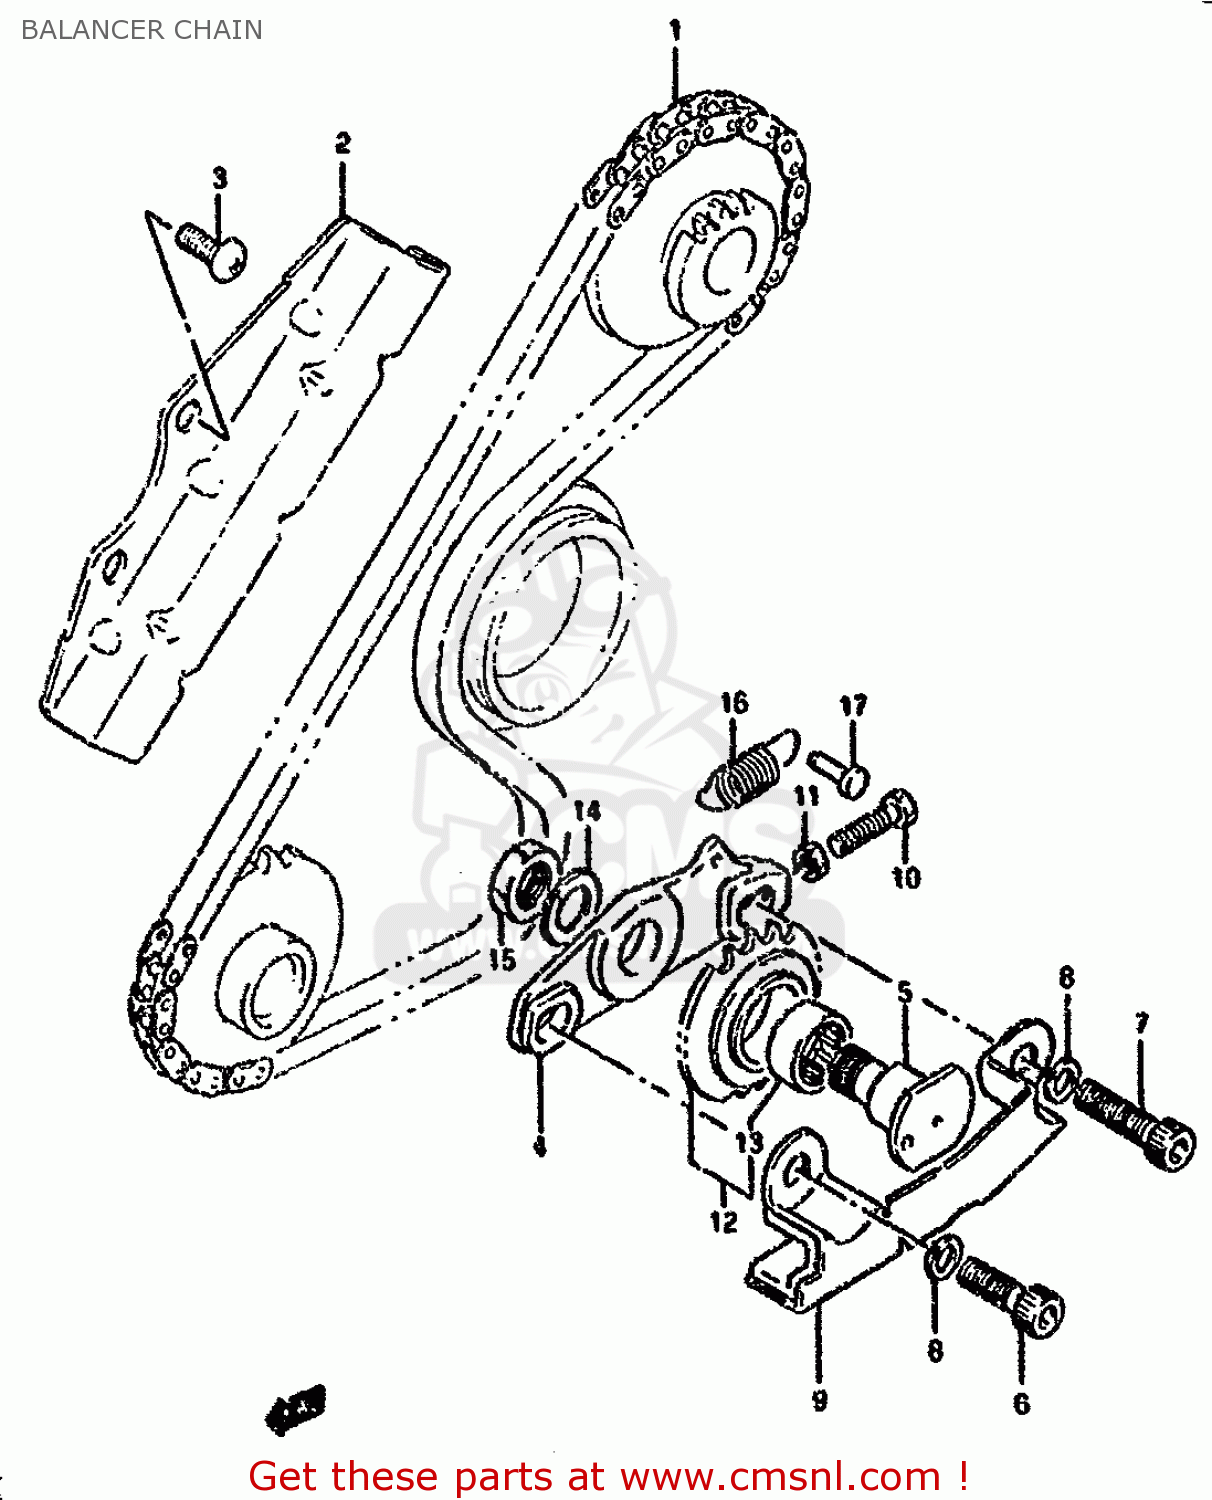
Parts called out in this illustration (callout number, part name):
1	CHAIN,BALANCER
2	GUIDE,BALANCER CHAIN
3	SCREW
4	BRACKET, CHAIN TENSIONER
5	SHAFT,BALANCER CHAIN TENSIONER
6	BOLT(8X22)
7	BOLT
8	WASHER,LOCK
9	GUIDE, CHAIN TENSIONER
10	BOLT
11	NUT
12	SPRKT,BALANCER CHAIN TENSIONER
13	BEARING(17X23X12)
14	WASHER,LOCK
15	NUT
16	SPRING
17	RIVET
